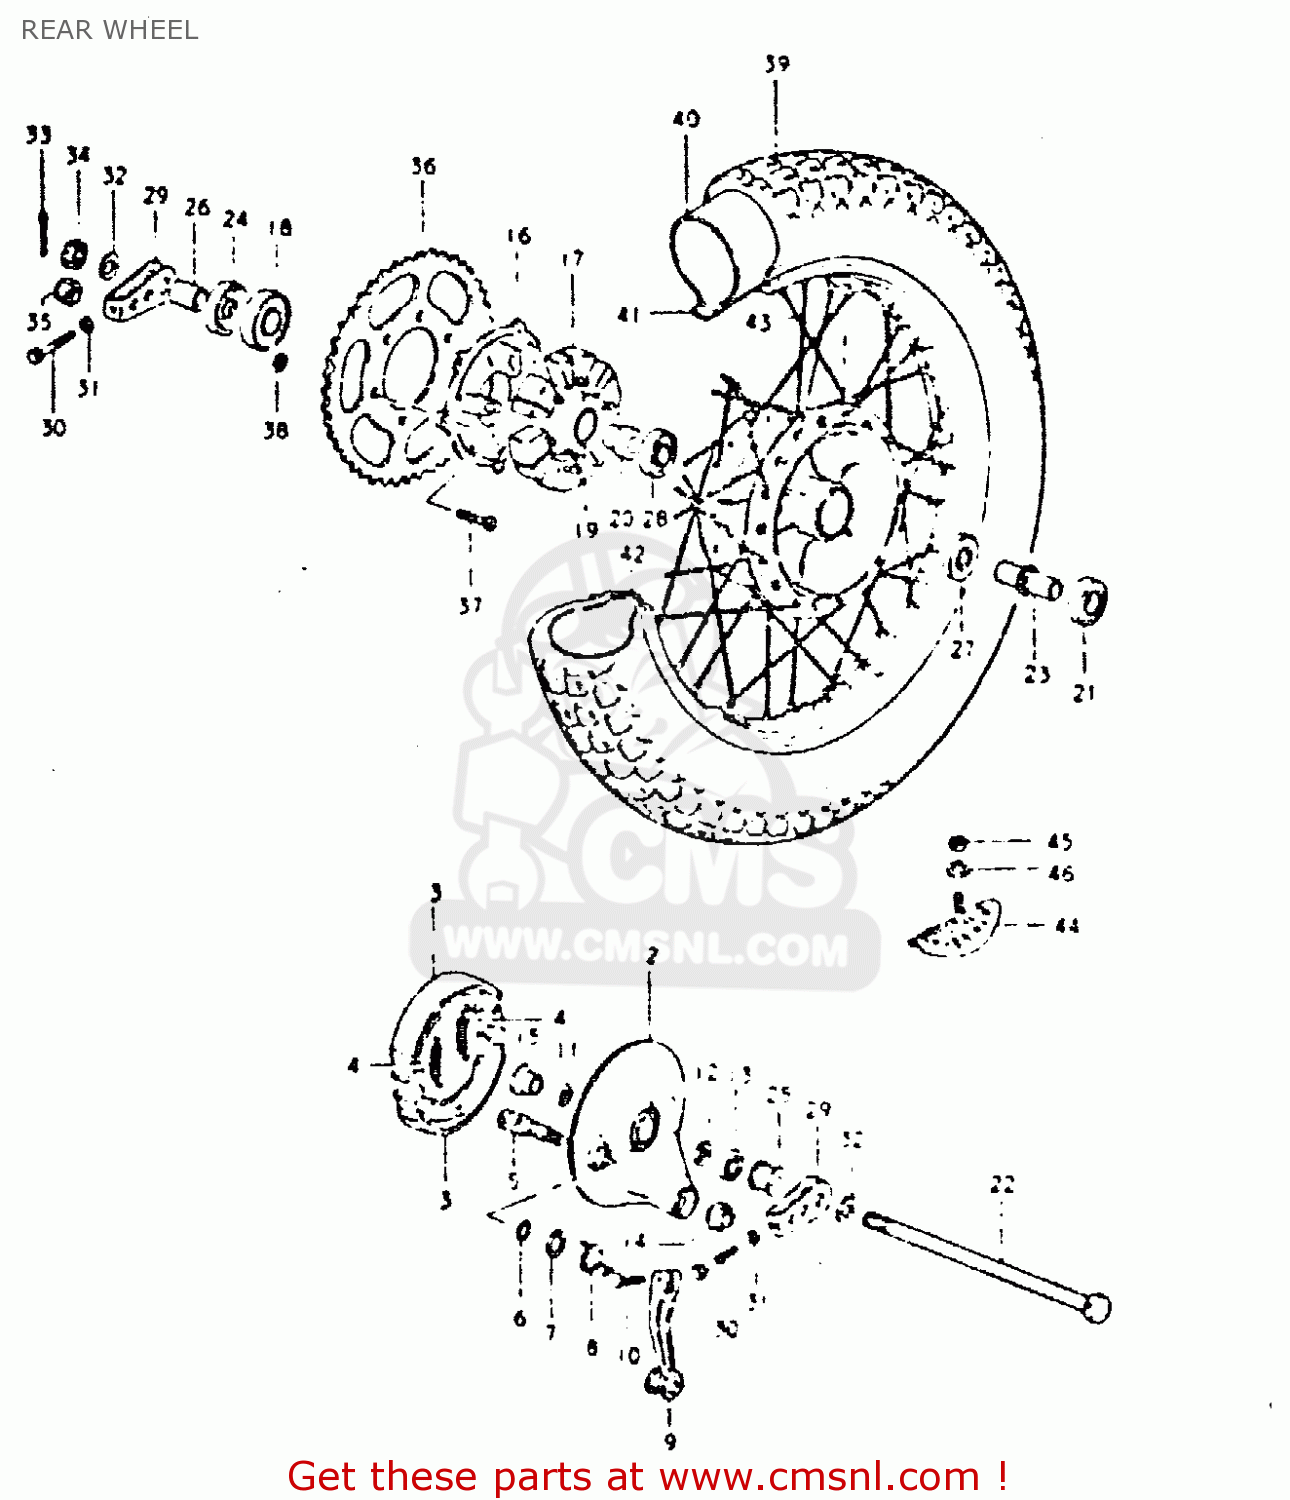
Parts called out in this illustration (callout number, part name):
1	DRUM,REAR HUB
2	PANEL,REAR HUB
3	SHOE,BRAKE (MCA)
4	SPRING
5	CAM,FRONT BRAKE
6	O-RING,BOSS
7	WASHER (15X24X1.6)
8	SPRING
9	LEVER,REAR BRAKE CAM
10	BOLT
11	BEARING(24X31X28)
12	THRUST WASHER
13	CVR,RR BRAKE AHR PNL DUST SEAL
14	SPHERICAL BEARING,TORQUE
15	SPACER,REAR HUB PANEL
16	DRUM,REAR SPROCKET MOUNT
17	ABSORBER,RR HUB SHOCK
18	BEARING
19	O-RING
20	SPACER,REAR SPROCKET DRUM
21	OIL SEAL
22	AXLE,REAR
23	SPACER,REAR HUB BEARING
24	SEAL,OIL(30.5X52X8)
25	SPACER,REAR AXLE,RIGHT
26	SPACER(17X30.5X16.3)
27	BEARING
28	BEARING
29	ADJUSTER,CHAIN
30	BOLT
31	NUT
32	WASHER (17X30X3.2)
33	PIN,COTTER
34	NUT
36	SPROCKET,RR NT
37	SCREW(8X33.5)
38	NUT
39	TIRE
40	TUBE,INNER
41	PROTECTOR,WHEEL,INNER
42	RIM,REAR WHEEL
43	SPOKE ASSY,RR WHEEL
44	STOPPER,BEAD
45	NUT
46	WASHER
